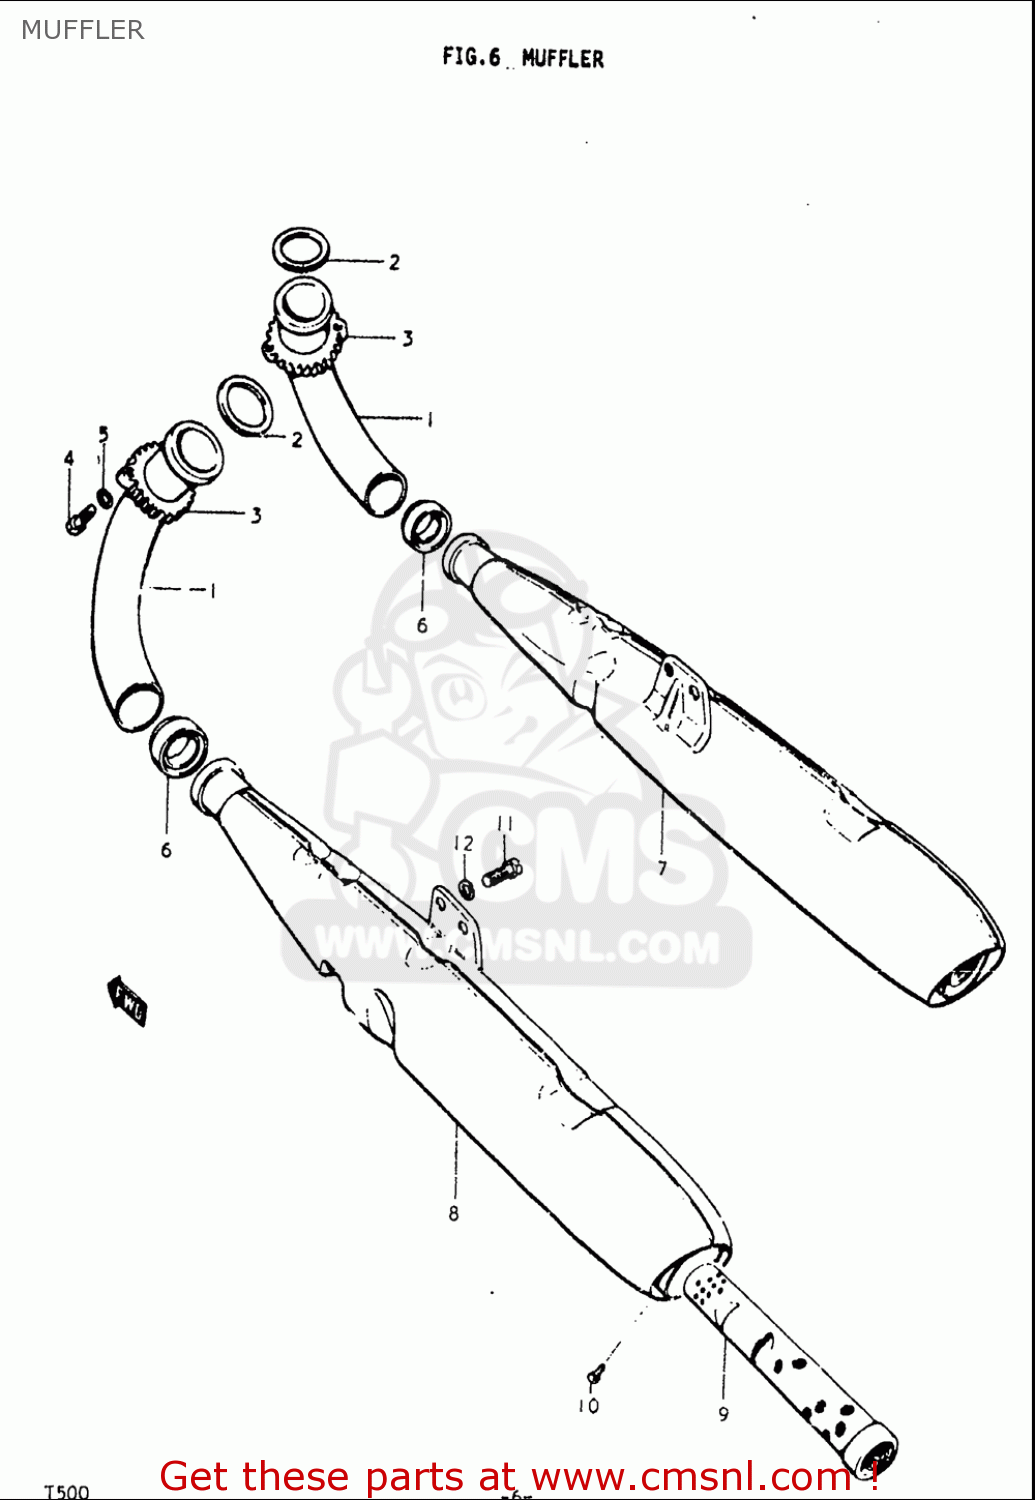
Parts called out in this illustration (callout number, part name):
1	PIPE,EXHAUST
2	GASKET,EXHAUST PIPE (NAS)
4	BOLT
5	WASHER,LOCK
6	CONNECTOR,MUFFLER
9	PIPE,BAFFLE
10	SCREW(5X6)
11	BOLT
12	WASHER,LOCK
